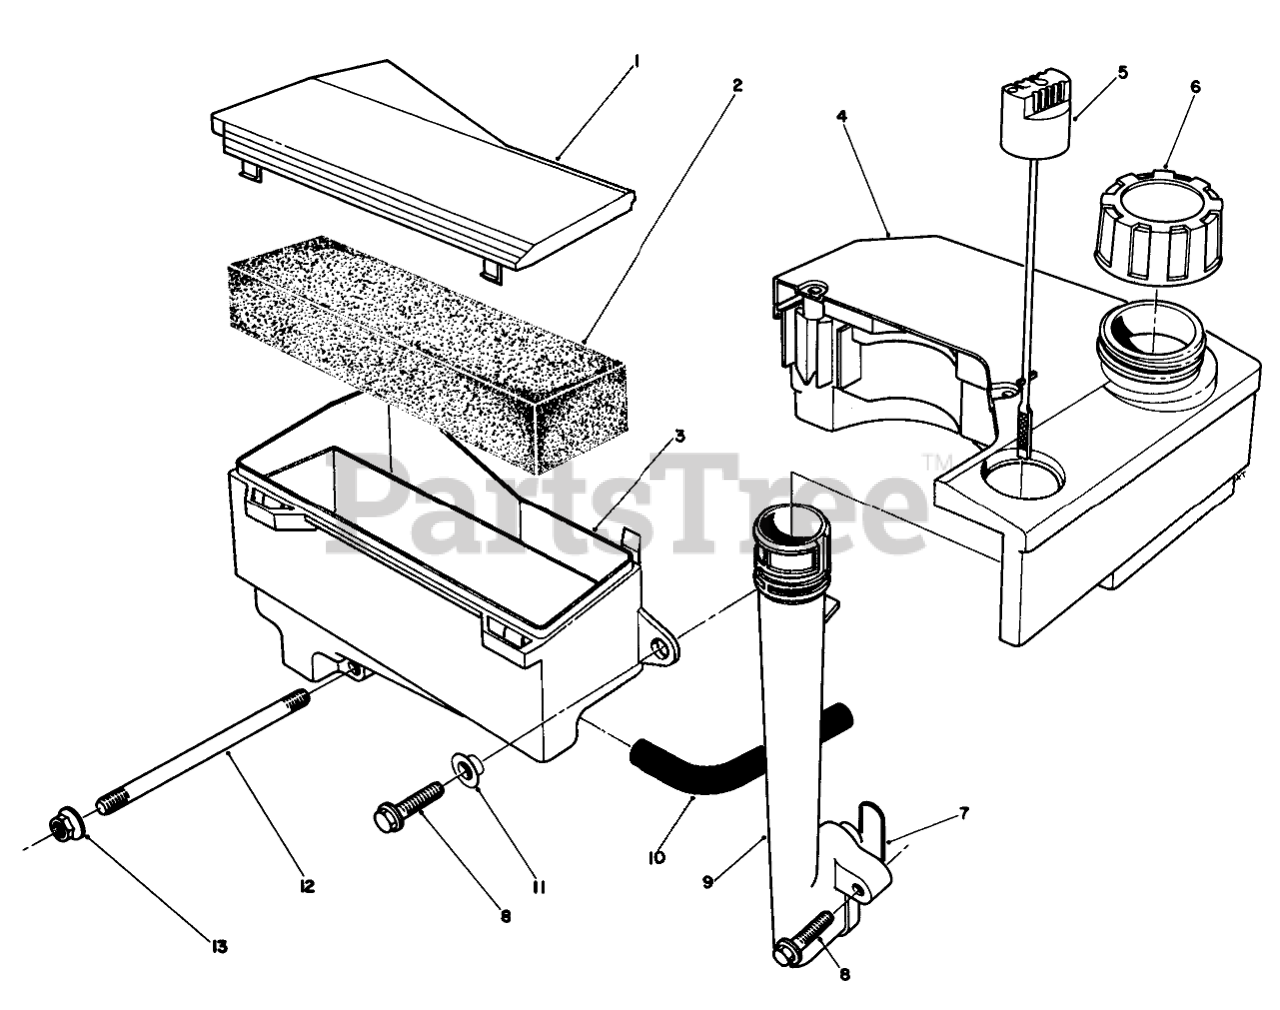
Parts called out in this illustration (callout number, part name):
1	AIR CLEANER CAP
3	Body-Air Cleaner
4	TANK ASM
5	Dipstick
6	GAS CAP ASM
7	O-RING
11	SPACER
12	Stud-Carburetor
